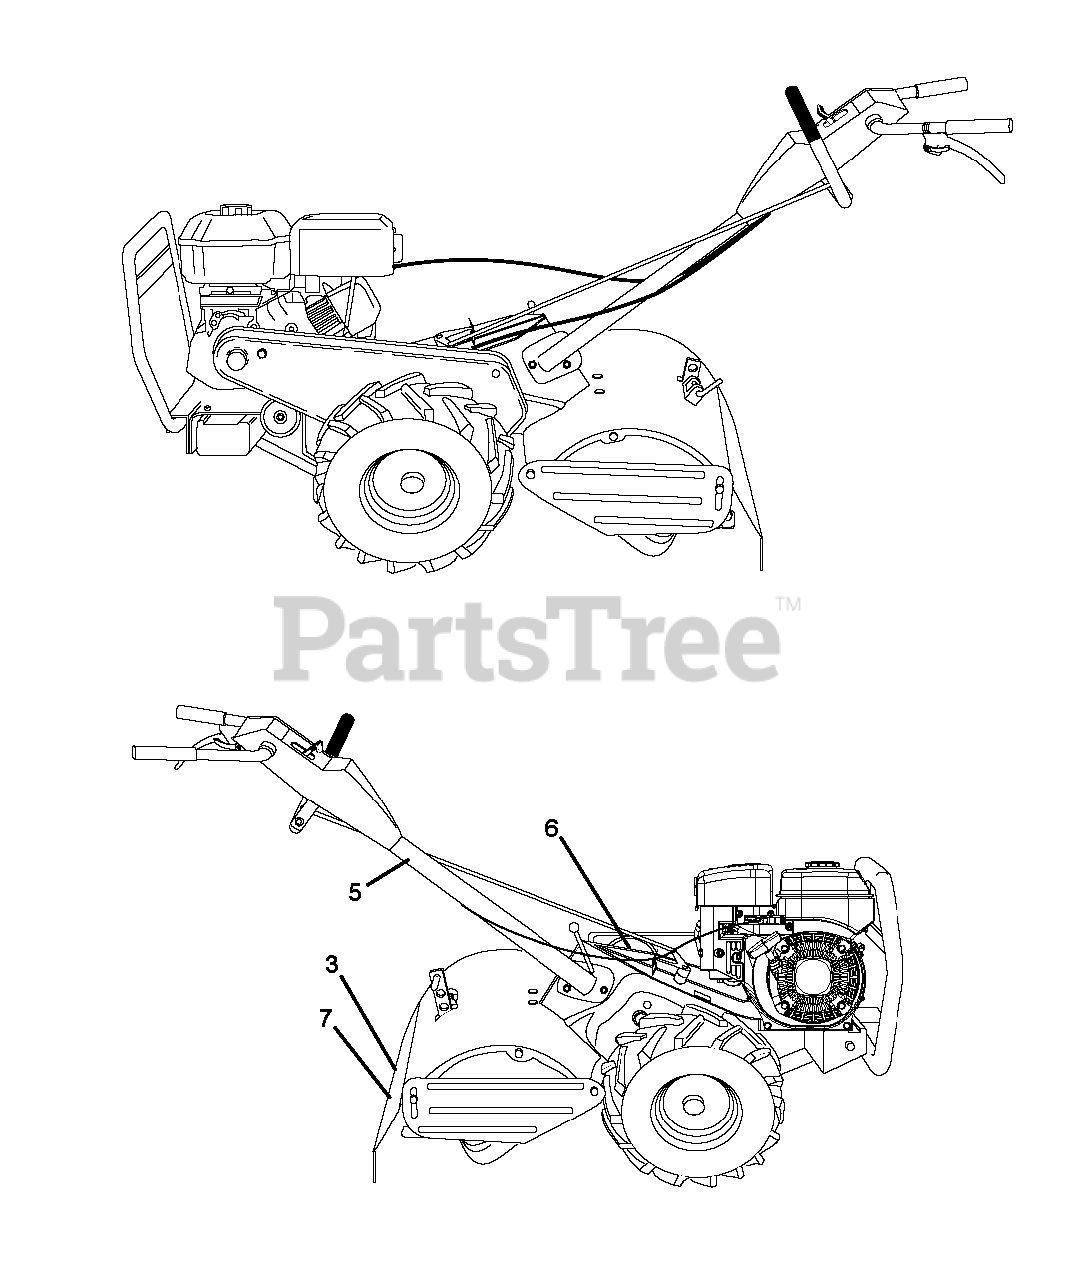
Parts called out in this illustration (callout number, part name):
3	DECAL EUROPE STANDARD CE
5	DECAL.PLACEMENT.HAND.SYMBOLS
6	DECAL, SHIFT INDICATOR
7	DECAL.WARNING.4-SYM.TILLER.INT
